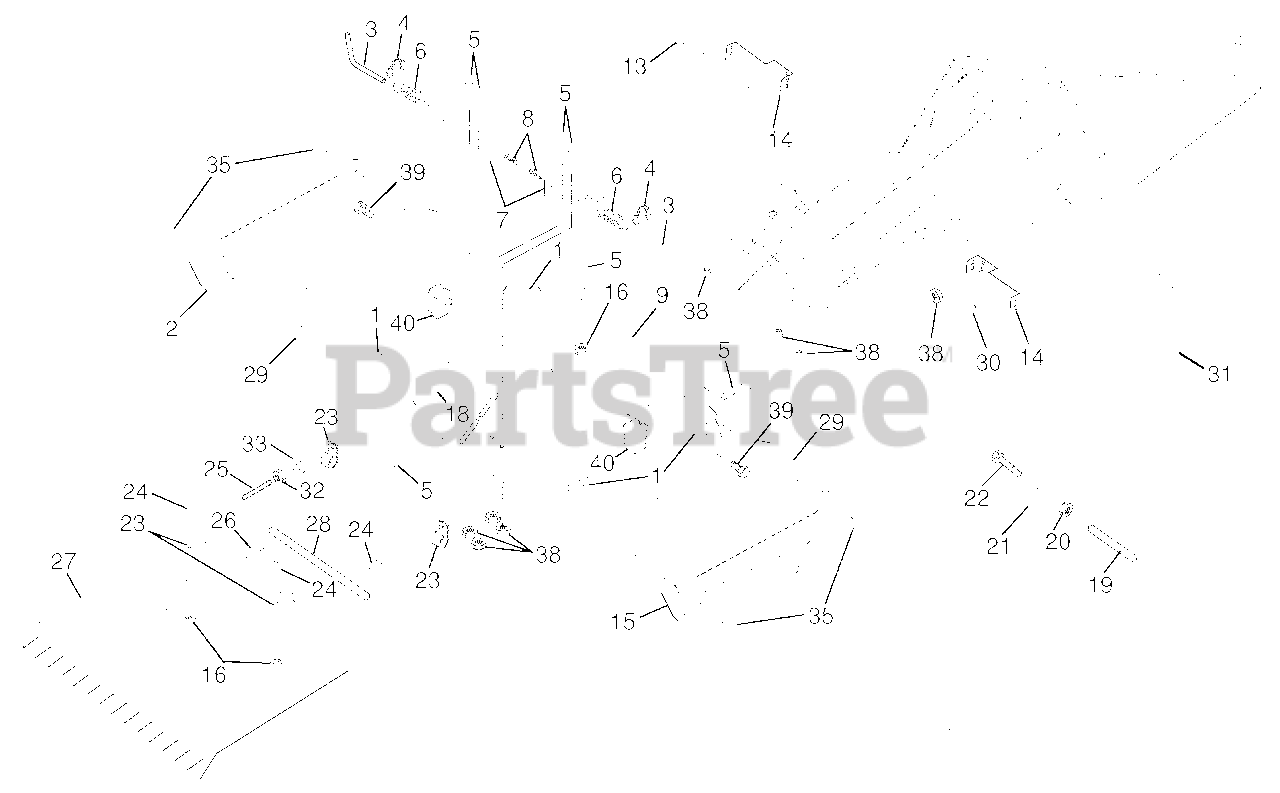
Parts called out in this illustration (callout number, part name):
1	HINGE SCREW
2	SHIELD, SIDE, OUTER, LH
3	Pin, Stake, Depth
4	Ring, Klip
5	Bolt, Carriage, Gr. 5 5/16-18
7	Bracket, Latch
8	Spring, Depth Stake
9	SHIELD, TINE
13	Bolt, Carriage 5/16-18 x 1-1/4
14	Bracket, Shield Tine
15	SHIELD, SIDE, OUTER, RH
16	Nut, Hex Flange 1/4-20 unc
18	Bolt, Carriage 1/4-20 x 1-1/4
20	Nut, Hex 3/8-16
21	Stake, Depth
22	Bolt, Hex 3/8-16 x 2
24	Bolt, Carriage 1/4-20 x 1/2
25	Cap, Vinyl
26	Pad, Idler
27	SHIELD, LEVELING
28	Pin, Hinge
29	SHIELD, SIDE
30	Nut, Hex, Flangelock
31	STAKE, DRAG
32	Nut, Fin, Hex 1/4-20 unc
33	Washer, Lock 1/4
35	BOLT.CARR.5/16-18 X 5/8 SHORT
38	Nut, Keps 5/16-18 unc
39	Screw, Sems, Thread Cutting 5/
40	NUT, HEX
